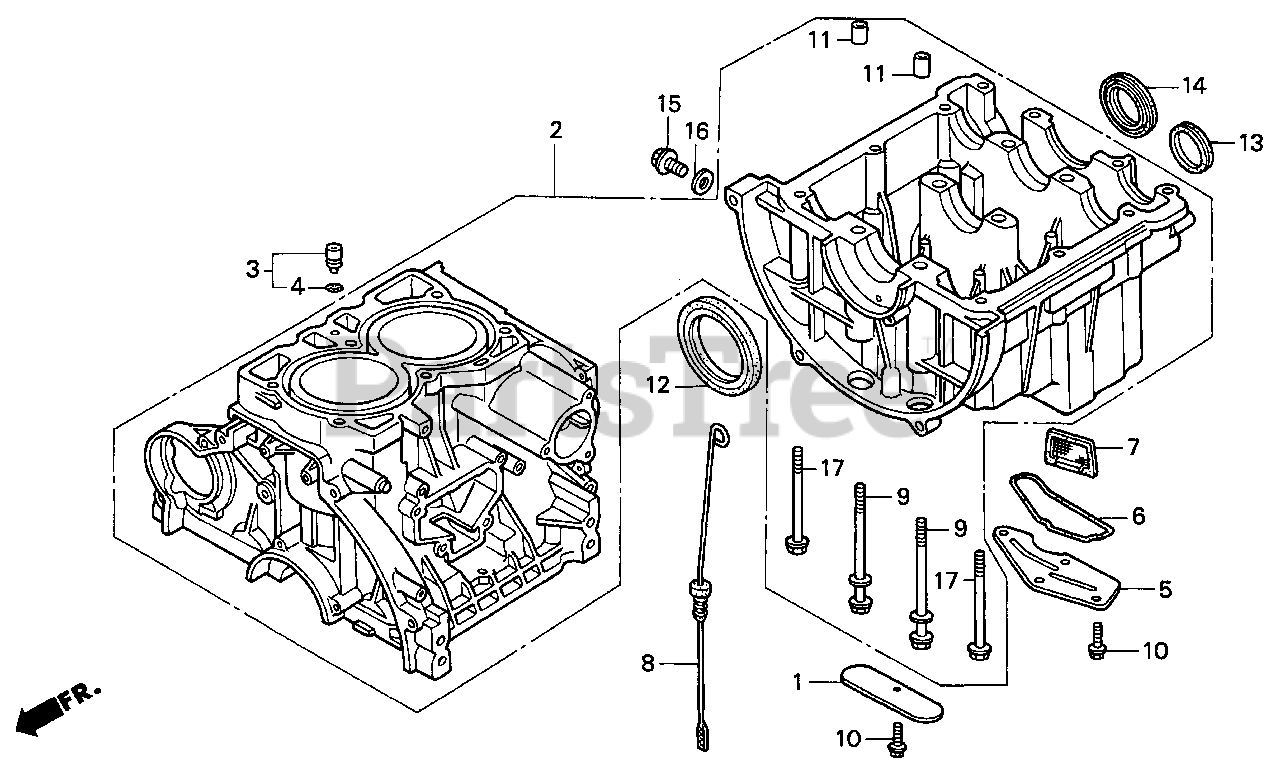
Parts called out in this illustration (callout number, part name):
1	PLATE (LOWER)
2	BLOCK ASSY., CYLINDER
3	ORIFICE ASSY., OIL PASSAGE
4	O-RING (4.8X1.9)
5	PLATE, OIL FILTER
6	O-RING, OIL PLATE
7	SCREEN, OIL FILTER
8	DIPSTICK, OIL
9	BOLT-WASHER (10X105)
10	BOLT, FLANGE (6X14)
11	PIN, DOWEL (13X20)
12	OIL SEAL (65X88X12)
13	PLUG, SEALING (42X7)
14	OIL SEAL (35X50X8)
15	BOLT, DRAIN PLUG (12MM)
16	WASHER, DRAIN PLUG (12MM)
17	BOLT, FLANGE (8X85)
